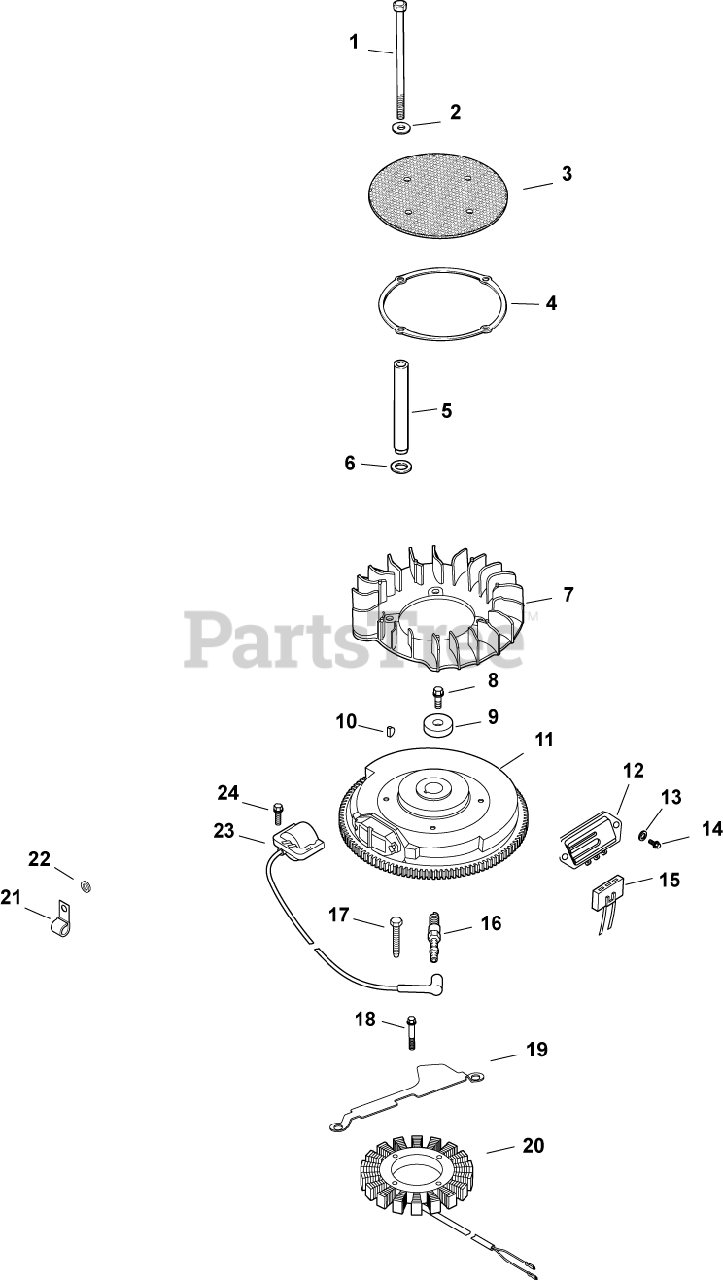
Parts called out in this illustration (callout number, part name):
1	SCREW, CAP M6X1.0X99.5
2	WASHER, FLAT 1/4" (O.D. 5/8")
4	RING, SUPPORT USE 25 141 08-S
6	WASHER, SPRING 10 MM
7	FAN (WITH HOLE)-USE 24 157 16-S
8	SCREW, FLG M10X1.5X45 - (#25086361S)
9	WASHER, FLAT 13/32"
10	KEY, 3/16" X 5/8"
11	FLYWHEEL, PAINTED-USE 24 025 59-S
12	REG/RECT-15 AMP (KM)-USE 41 403 10-S
13	WASHER, FLAT 3/16"
14	SCREW, PHL HD #11-16X7/8"
15	CONNECTOR, BODY (KM)-USE 25 155 41-S
16	PLUG, SPARK (STD)
17	SCREW, M5X0.8X25 - (#25086402S)
18	SCREW, SKT SET #10-24X1/4"
19	BRACKET, STATOR WIRE
20	KIT, 15 / 20 AMP STATOR
21	CLIP, CABLE
22	WASHER, FLAT 1/4" (O.D. 1/2")
23	MODULE, IGNITION-USE 24 584 45-S
24	SCREW, FLG THD FRM M5X.8X20-(#25086399S)
